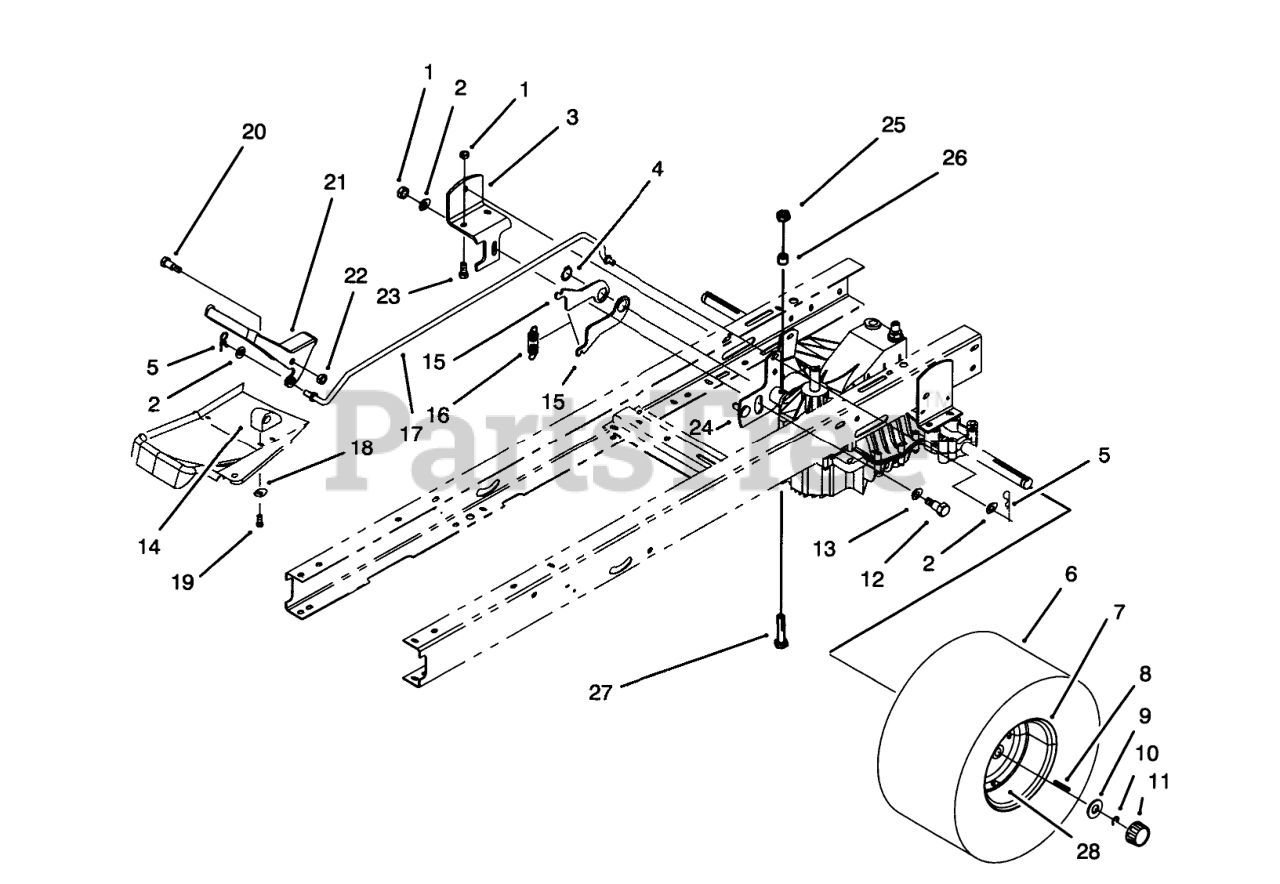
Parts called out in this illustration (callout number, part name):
1	NUT-LOCK, NI
2	WASHER-PLAIN
3	NEUT ADJUSTING BRKTB
4	RING-SNAP
5	PIN-COTTER
6	TIRE 18 X 9.50 X 8
8	KEY-SQUARE
9	WASHER-PLAIN
10	E-RING
11	CAP-HUB
12	BOLT-SHOULDER
13	THRUST WASHER
14	BLOCK-PIVOT
15	NEUTRAL RETURN LEVER
16	SPRING-EXTENSION
17	SPEED CONTROL ROD
18	WASHER-FLAT
19	SCREW-PLASTITE
20	SCREW-SHOULDER, HH
21	Pedal-Speed Control
22	NUT-LOCK, NI
23	SCREW-HH
24	SPEED CNTRL LEVER WA
25	NUT-LOCK, NI
26	LOCK SPACER
27	SCREW-HSH
28	STEM-VALVE
